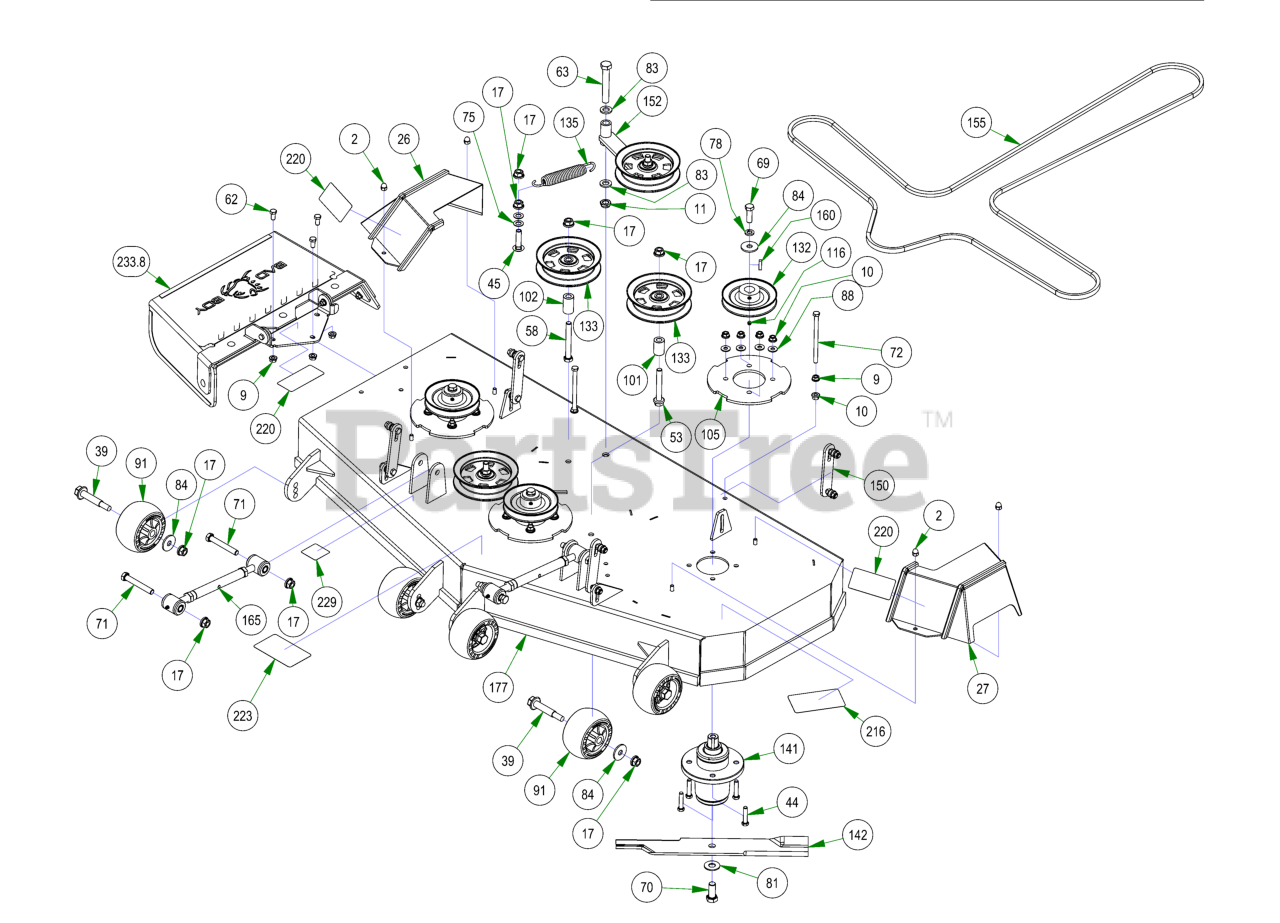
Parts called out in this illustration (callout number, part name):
2	5/16-18 ACORN NUT HIGH-CROWN ZC
9	3/8-16 HEX SERRATED FLANGE NUT HARD/ZINC
10	3/8-16 NYLON INSERT FLANGE LOCKNUT (GR.F) ZINC
11	5/8-11 NYLON INSERT JAM LOCKNUT ZINC
17	1/2-13 NYLON INSERT FLANGE LOCKNUT ZINC
26	2021 Maverick 54”/60” RH Pulley Cover
27	2021 Maverick 54”/60” LH Pulley Cover
39	Deck Wheel Bolt
44	3/8-16 X 1-3/4 HEX C/S (GR.5) ZC
45	1/2-13 X 2 CARRIAGE BOLT ZINC
53	1/2-13 X 3-1/2 HEX FLANGE BOLT (GR.8) ZINC
58	1/2-13 X 4 HEX CAP SCREW (GR.8) ZINC YELLOW
62	3/8-16 X 3/4 HEX CAP SCREW (GR.5) ZINC
63	5/8-11 X 4 HEX CAP SCREW (GR.8) ZINC YELLOW
69	1/2-20 X 1-1/2 HEX CAP SCREW (GR.5) ZINC
70	5/8-18 X 1-1/2 HEX CAP SCREW (GR.8) ZINC YELLOW
71	1/2-13 X 3-1/2 HEX CAP SCREW (GR.5) ZINC
72	3/8-16 X 5-1/2 HEX CAP SCREW (GR.5) ZINC
75	.517 SQ WDTH ID X .937 OD X .060 THICK F/W PHOS/OIL
78	1/2 SPLIT LOCKWASHER (GR.8) ZINC/YELLOW
81	5/8 USS FLAT WASHER (1-3/4" OD) GR.8 ZINC YELLOW
83	.635 ID X 1.120 OD X .140 THICK FLAT WASHER NYLON
84	1/2 BELLEVILLE WASHER (1-5/8 OD X .140 THK) ZINC
88	5/16 USS FLAT WASHER (7/8 OD) ZINC
91	Deck Wheel
101	.502 ID X .750 OD X 1.500 Long Spacer
102	1 3/4" Pulley Spacer
105	Deck Spindle Support Plate
116	5/16-24 X 1/4 SOCKET SET SCREW (CUP PT) PLAIN
132	5.25" Deck Spindle Pulley
133	5-3/4 Idler Pulley
135	Deck Idler Spring
141	OUTLAW SPINDLE ASSEMBLY
142	54" Fusion Blade for ZT/Mav/Outlaw/Revolt
150	Deck Hanger Assembly
152	2017 MZ/ZT Deck Idler Assembly
155	B155.75 Deck Belt
160	1/4 X 1 SQ MACHINERY KEY 1018 STL PLN
165	2018 Maverick Turnbuckle (Top Link)
177	54 ZT Welded Deck
216	2018 54" Deck Decal
220	Danger Decal-Spindle/Discharge
223	Deck Belt Route Decal
229	Deck Impact Patent Decal 9591803
233	Discharge Chute Assembly
